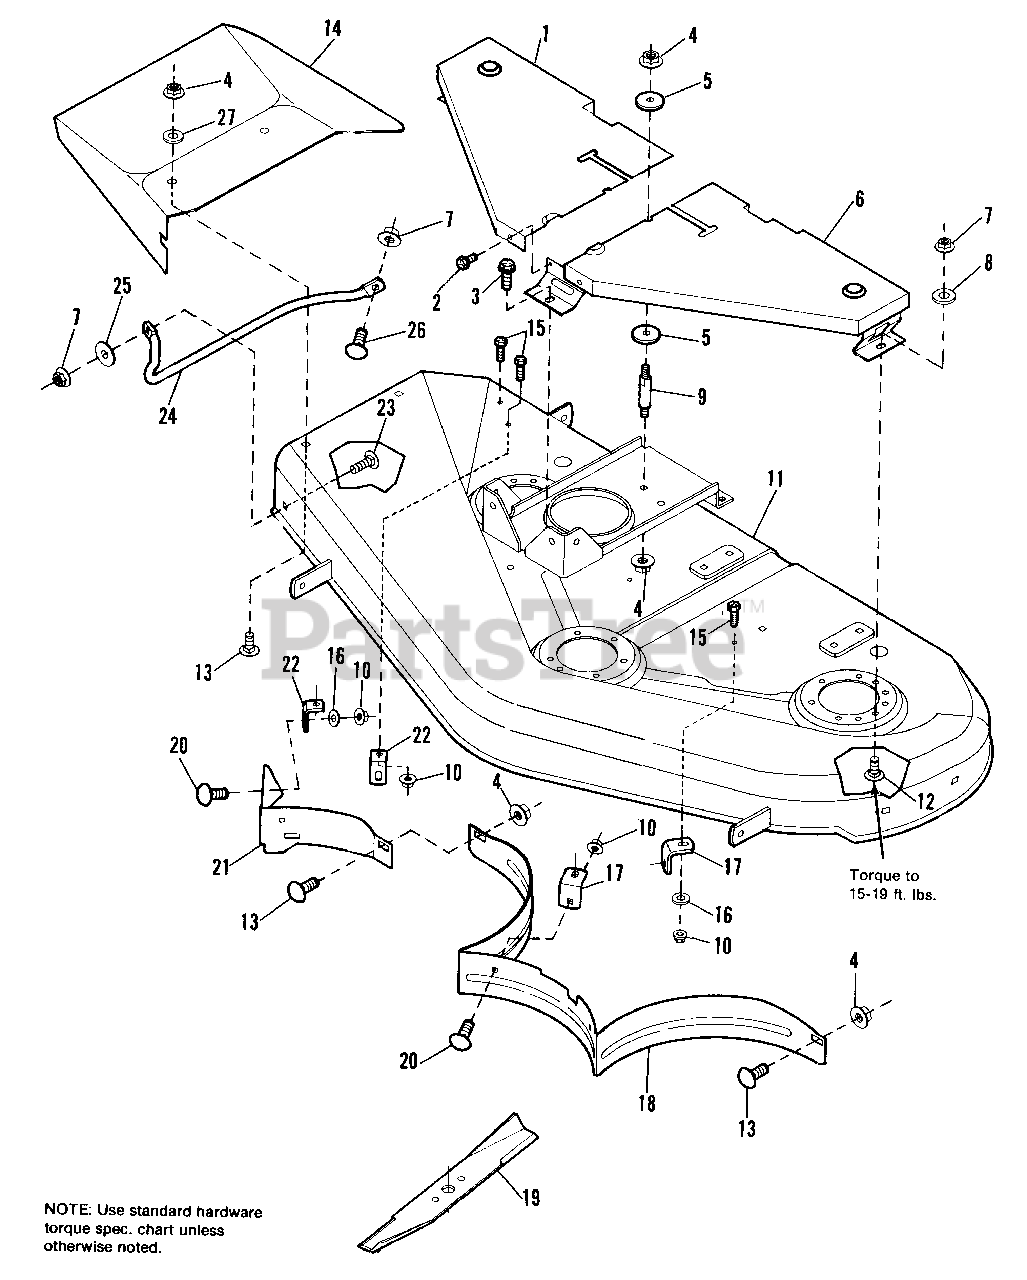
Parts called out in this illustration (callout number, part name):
1	COVER ASSY., Belt, R.H. (1691662)
1	COVER ASSY., Belt, R.H. (1691665)
2	SCREW, Taptite, 1/4-20 x 3/8
3	SCREW, Taptite, 5/16 x 1/2
4	NUT, Hex Whizlock, 3/8-16
5	WASHER, 3/8
6	COVER ASSY., Belt, L.H. (1691662)
6	COVER ASSY., Belt, L.H. (1691665)
7	NUT, Hex, Whizlock, 5/16-18
8	WASHER, 3/8
9	STUD, Double Hex
10	NUT, Hex, Whizlock, 1/4-20
11	HOUSING ASSY. (1691662)
11	HOUSING ASSY. (1691665)
12	SCREW, Taptite, 5/16-18 x 1
13	CARRIAGE BOLT, 3/8-16 x 3/4
14	DEFLECTOR ASSY. (1691662)
15	CAPSCREW, Hex, 1/4-20 x 5/8
16	WASHER, 1/4
17	CLIP, Baffle
18	BAFFLE
20	CARRIAGE BOLT, 1/4-20 x 5/8
21	BAFFLE, Discharge
22	CLIP, Baffle
23	CARRIAGE BOLT, 5/16 x 1-1/4
24	GUARD, Mower Discharge
25	WASHER, 5/16
26	CARRIAGE BOLT, 5/16-18 x 3/4
27	WASHER, 3/8
